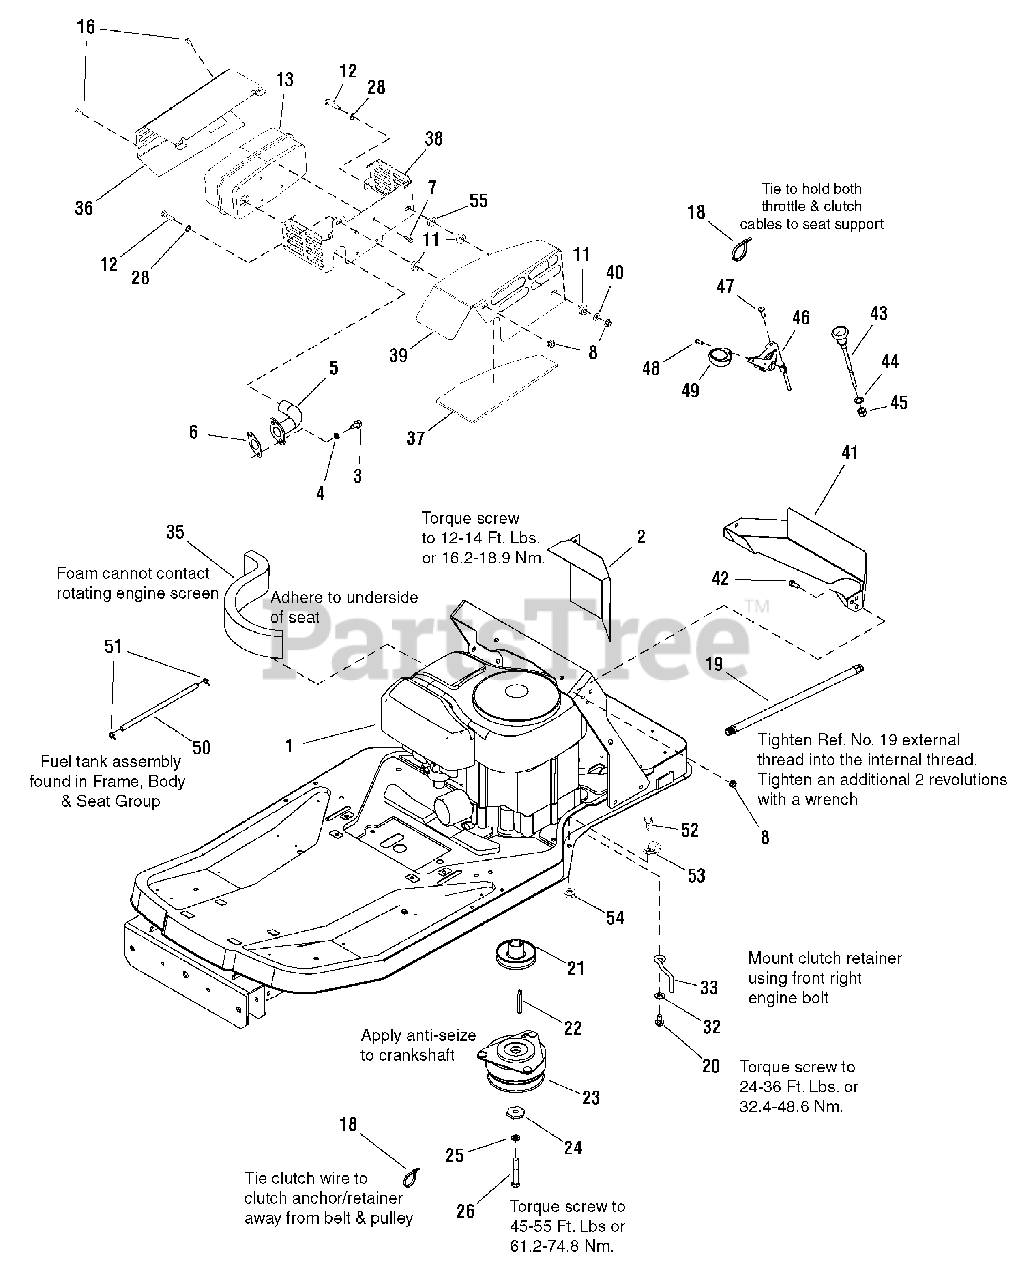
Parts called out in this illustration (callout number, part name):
1	* ENGINE, 20 HP B&S ELS
2	HEAT SHIELD, Inner
3	SCREW, 5/16-18 x 3/4" Hex Head Cap, GR8
4	LOCKWASHER, Spring 5/16", Black
5	WELDMENT, Exhaust Pipe
6	GASKET, Exhaust
7	SCREW, 1/4-20 x 5/8" Hex Whiz Lock Flange
8	NUT, 5/16-18 Hex Flange Lock Large, Black
11	SPACER, .390 ID x .9 OD x .34 LG, Powdered Metal
12	SCREW, 5/16-18 x 1-1/4" Hex Head Cap, GR5, Black
13	MUFFLER ASSEMBLY, Single
14	SCREW, 5/16-18 x 1-1/2" Hex Head Cap, GR5, Black
16	SCREW, #10 x 1/2" Hex Washer Head Self-Tap
18	TIE, Self Locking 3-5/8" Long
19	HOSE, Oil Drain, 16-1/2" Long
20	SCREW, 3/8-16 x 1-1/4" Hex Washer Head Taptite
21	PULLEY ASSEMBLY, Engine
22	KEY, Square, 1/4 x 1/4 x 29/32 Hardened
23	CLUTCH, Electric
24	WASHER, Hex, .453 I.D. x 1-1/2"
25	LOCKWASHER, Spring, .438
26	CAPSCREW, Hex Head, 7/16-20 x 3", GR 5
28	WASHER, 5/16" (.34 I.D. x 3/4" O.D.)
32	WASHER, 3/8", (.41 I.D. x .87 O.D. x .08 Thick)
33	RETAINER, Clutch
35	SEAL, Foam Air Duct, 1 x 2-1/2, 12" Long
36	HEAT SHIELD, Single
37	INSULATION SHIELD, Top Muffler
38	MUFFLER BRACKET/HEAT SHIELD
39	GUARD, Muffler
40	NUT, 5/16 Push Pal
41	AIR DUCT, Inlet
42	SCREW, 5/16-18 x 3/4" Hex Head Cap, Black
43	CABLE, Choke, 54"
44	WASHER, 3/8" Internal Tooth Lock
45	NUT, 3/8-24 Hex
46	CONTROL, Throttle B&S Intek
47	SCREW, 1/4-20 x 5/8" Pan Head Taptite Torx
48	SCREW, #10-16 x 3/4" Pan Head Taptite Combo
49	KNOB, Throttle, Red
50	HOSE, Fuel, 1/4" I.D. x 19-1/2" Low Perm
51	CLAMP, Hose
52	CAPSCREW, 5/16-18 x 3/4" Hex Flange Whiz Lock
53	CLIP, Harness, 5/8"
54	NUT, 5/16-18 Hex Flange Lock, Small - Black
